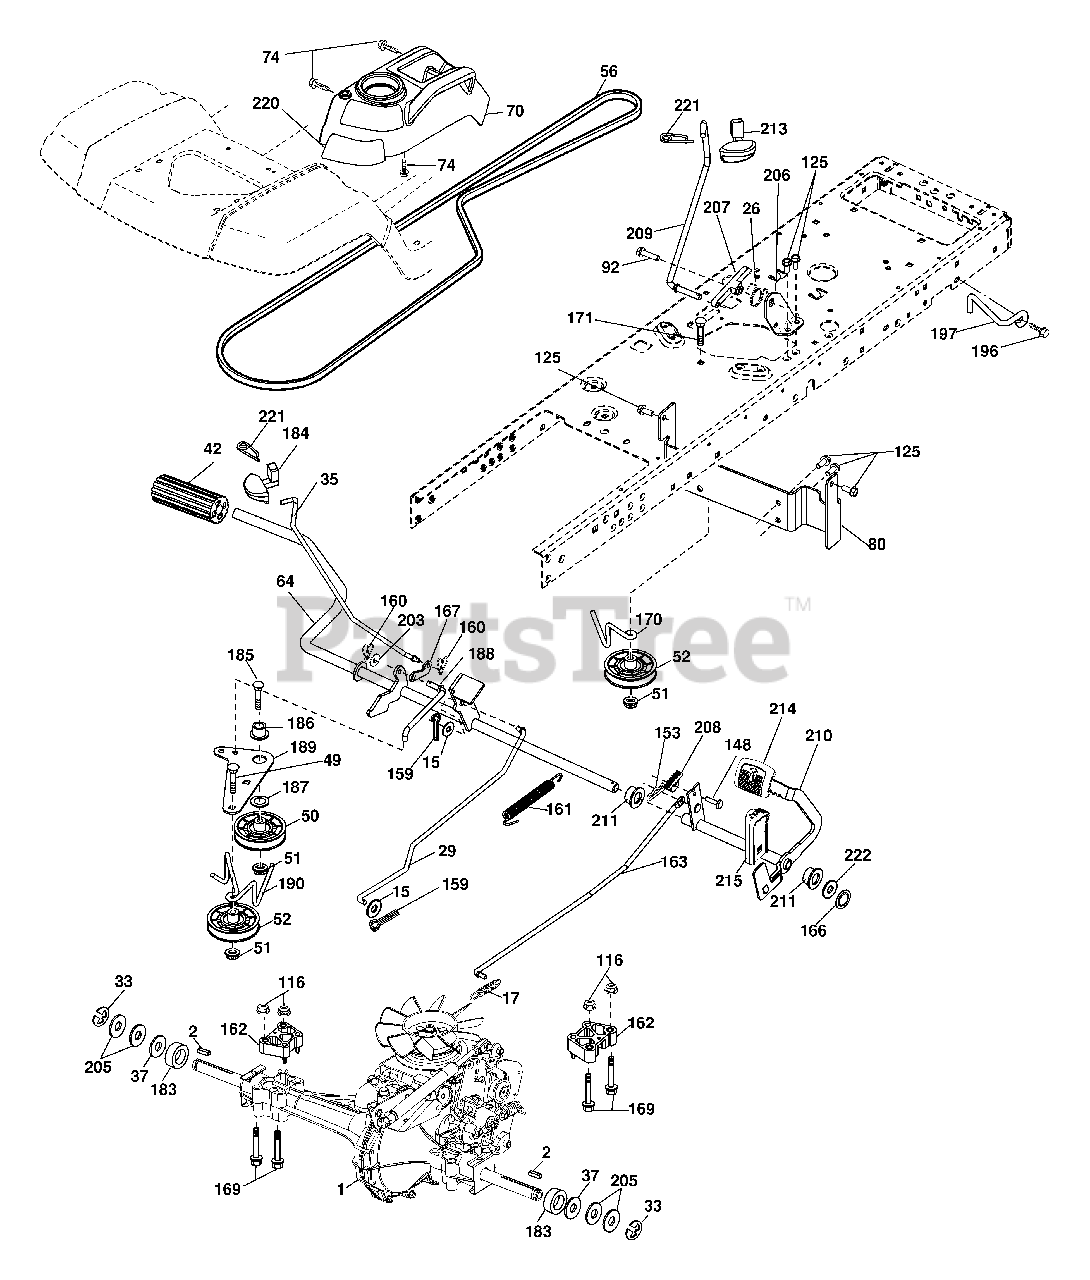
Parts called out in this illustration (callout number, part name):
15	Washer 13/32 x 13/16 x 16 Ga.
17	Spring, Brake
26	Spring Return Cruise
29	Rod, Brake
35	Rod, Brake, Park
42	Cover, Foot Pedal
50	Pulley Idler Flat
51	Lock Nut 3/8-16
52	Idler V-Groove 910" Offset
56	V-Belt, Drive
64	Shaft Asm. Pedal Brake Control
70	Console Asm.
74	Screw Hex Washer Hi-Lo 1/4 x 1/2 unc
80	Bracket Strap Torque
92	Bolt Fin Hex 5/16-18 unc x 1.25
116	Nut Lock Hex Flange 5/16-18
125	Screw 5/16-18 x 3/4
148	Screw 3/8-16 x 3/4
153	Retainer Spring
159	Pin Cotter 1/8 x 3/4
160	Retainer Clip
161	Spring, Return, Clutch
162	Spacer Transaxle
163	Rod Pedal Control
166	Nut Push .625
167	Latch Brake Parking
169	Bolt Hex Flngd 5/16-18 x 3.75
170	Keeper Belt Centerspan
183	Spacer Split
184	Handle Parking Brake
186	Spacer Retainer
187	Washer
188	Link Clutch Ground Drive
189	Bellcrank Ground Drive
190	Keeper Bellcrank Ground Drive
196	Screw 3/8-16 x 1
197	Bracket Clutch Anti-Rotation
203	Washer 11/32 x 11/16 x 16 Ga.
206	Bracket Mount Latch Cruise
207	Latch Control Cruise
208	Bolt Sector Control Cruise
209	Rod Control Cruise
210	Rocker Asm. Pedal Control
211	Bearing Nylon
213	Knob Control Cruise
214	Pad Pedal Forward
215	Pad Pedal Reverse
220	Reflector RH
221	Retainer Spring Clip Handle
222	Washer Flat
